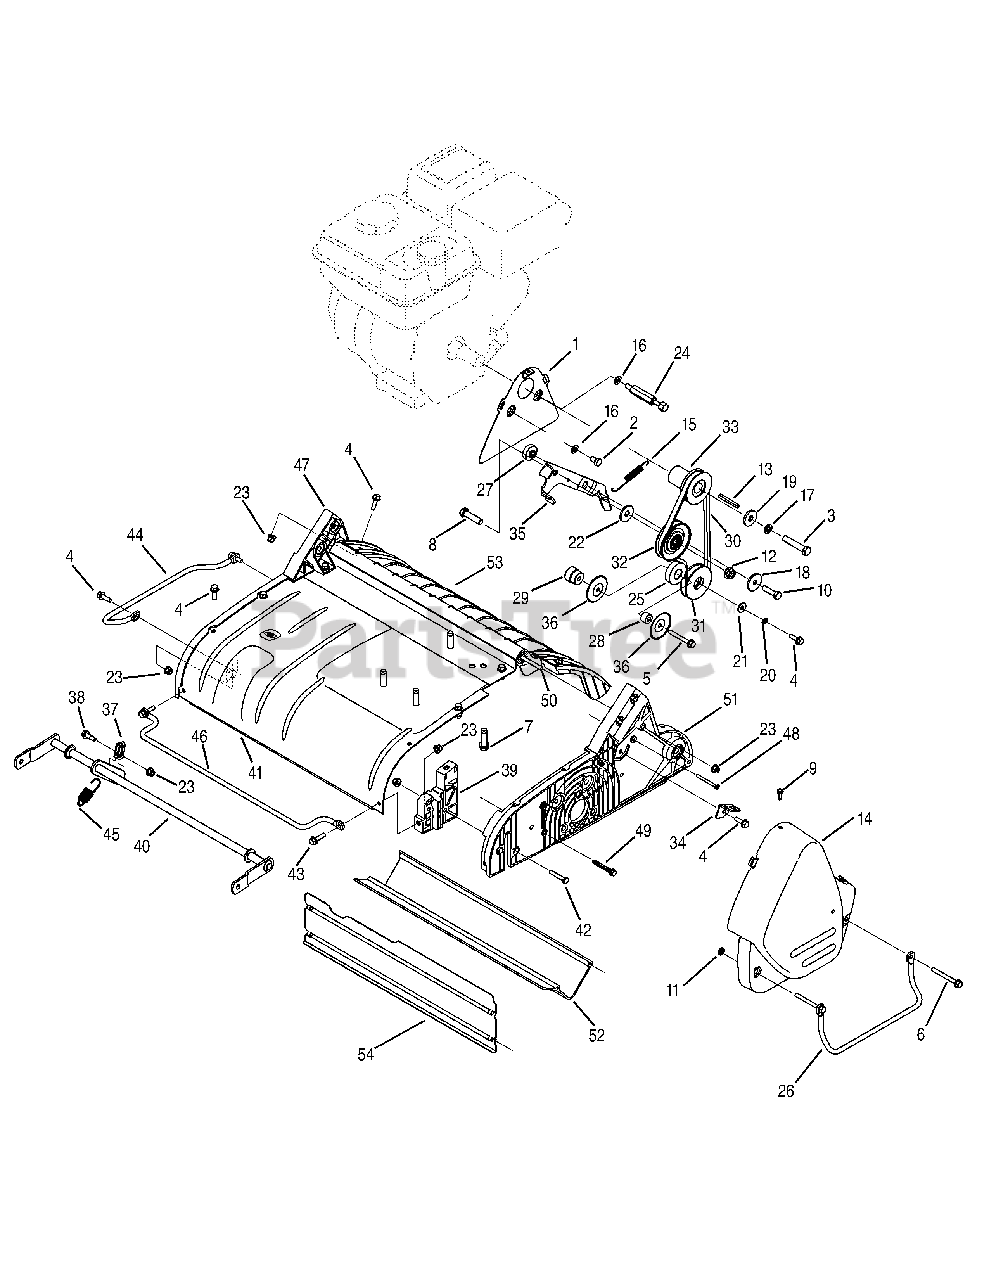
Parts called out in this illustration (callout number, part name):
1	Pulley Guard Assembly
2	Hex Screw, 5/16 - 24
3	Hex Screw, 3/8 - 24
4	Screw, M6 - 1 x 20.0
5	Screw, M6 - 1
6	Screw, M6 - 1
7	Sems Screw, 3/8 - 16
8	Hex Screw, 3/8 - 16
9	Screw, .625
10	Hex Screw, M8 - 1.25
11	Jam Nut, 1/4 - 20
12	Flange Lock Nut, 3/8 - 16
13	Square Key, 3/16 x 1.75
14	Pulley Cover
15	External Spring
16	Lock Washer, 5/16
17	Lock Washer, 3/8
18	Flat Washer, .330 x 1.25 x .120
19	Flat Washer, .395 x 1.12 x .14
20	Lock Washer
21	Flat Washer, 6.4 ID
22	Flat Washer, 10.5 ID
23	Flange Lock Nut
24	Belt Retainer Screw
25	Ball Bearing
26	Bumper Side
27	Idler Spacer
28	Bearing Spacer, 6.6 x 16.7 x 11.6
29	Idler Spacer, 6.5 x 22.3 x 23
30	V Belt
32	Pulley, 2 x 2.75 x .625
33	Pulley, .75 ID x 2.14
34	Cable Bracket Mount
35	Idler Arm
36	Washer Bearing
37	Cable Retainer Bracket
38	Shoulder Spacer, 7.13 x 11.50
39	Wheel Cradle Bracket Assembly
40	Height adjustment Bracket Assembly
41	Frame
42	Screw, M6-1 x 35.0
43	Screw, M6 - 1 x 25.0
44	Right Hand Bumper Side
45	External Spring, 17.6mm x 54.0mm
46	Front Bumper
47	Right Hand Frame Assembly
48	Tap Screw
49	Screw, 1/4 - 20
50	Deflector Mounted Rod
51	Left Hand Frame Assembly
52	Rear Baffle
53	Deflector
